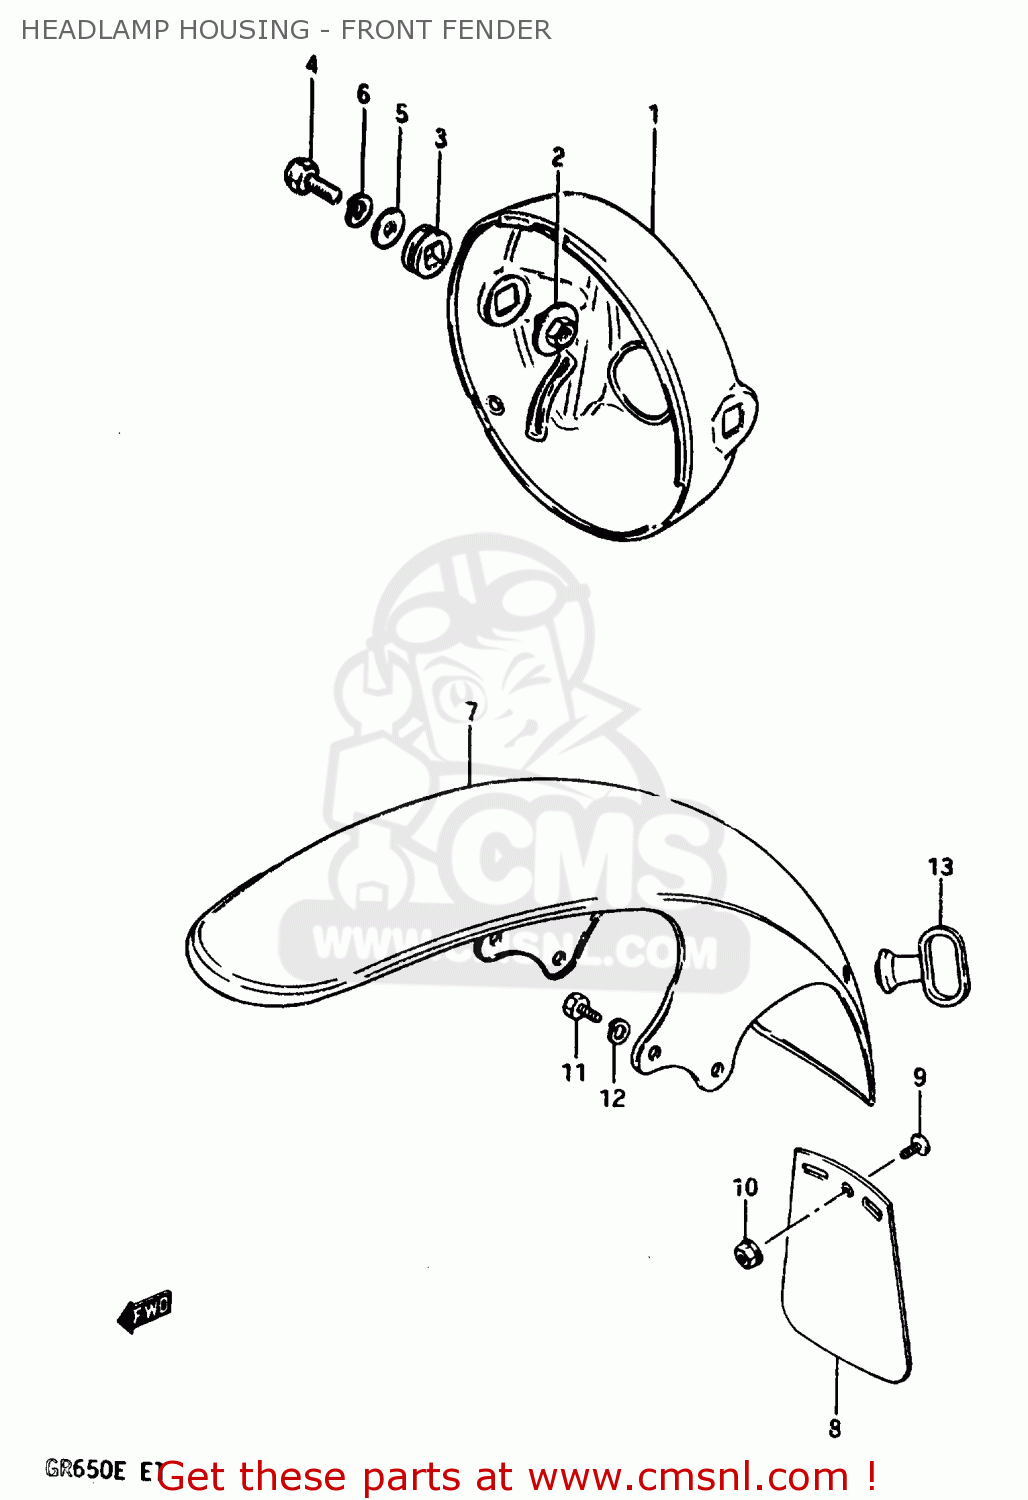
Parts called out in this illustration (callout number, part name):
1	HOUSING ASSEMBLY,HEADLAMP
2	SPACER,HEADLAMP HOUSING
3	CUSHION,HEADLAMP HOUSING
4	BOLT
5	WASHER
6	LOCK WASHER
7	FENDER, FRONT
8	MUD FLAP,FRONT FENDER
9	SCREW
10	NUT
11	BOLT
12	LOCK WASHER
13	GUIDE,CABLE
